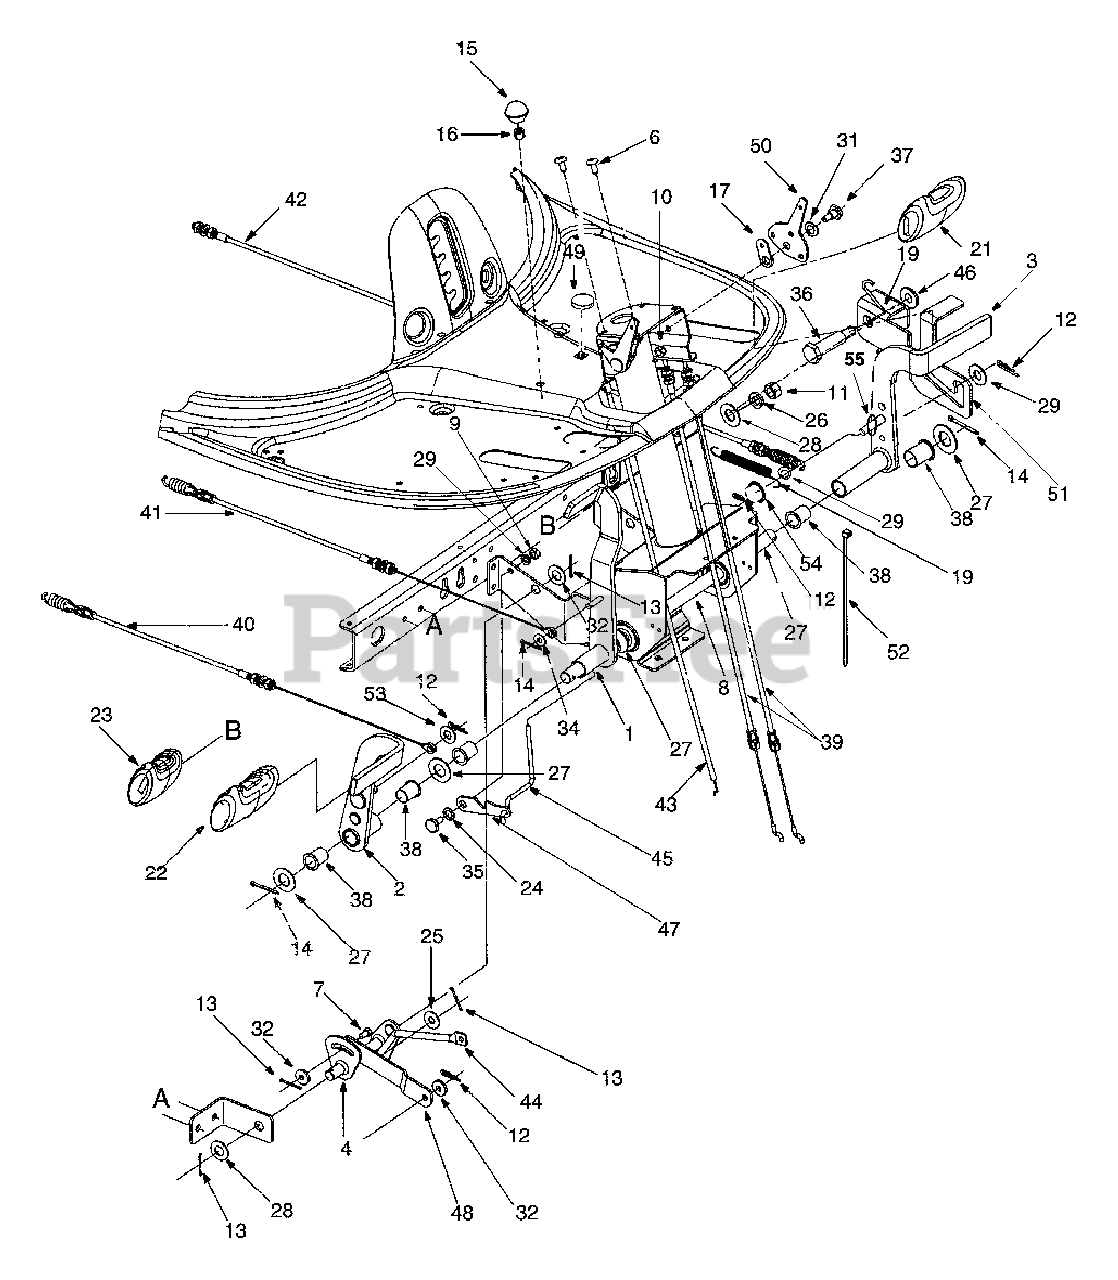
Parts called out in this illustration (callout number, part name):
7	Clevis Pin
8	Shaft
9	Hex Nut 1/4-20
10	Lock Nut 1/4-20
11	Hex Nut 3/8-16
12	Internal Cotter Pin
13	Hairpin Clip
14	Hairpin Clip
15	Ball Knob
16	Snap-on Bushing
17	Stop Lever
19	Torsion Spring
21	Deck Pad
22	Drive Pad
23	Brake Pad
24	Flat Washer 3/8 X .620 X .033
25	5/16 Washer
26	Lock Washer
27	Flat Washer
28	Flat Washer .510 X 1.00 X .060
29	Flat Washer .406 x 1.25 x .10
31	Spring Washer
32	Flat Washer
34	Flat Washer .271 X .630 X .065
35	Shoulder Screw .375 Dia X .18
36	Shoulder Screw
37	Shoulder Screw .375 X .380 X 1/4-20
38	Flange Bearing
39	Shift Cable
40	Variable Drive Cable
41	Brake Cable
42	Deck Cable
43	Throttle Choke Cable: 67"
44	Brake Rod
45	Brake Lock Out Rod
46	Shoulder Spacer
50	Shift Lever
53	Flat Washer .406 I.D. x .875 O.D.
54	Push Cap
55	Flat Washer
